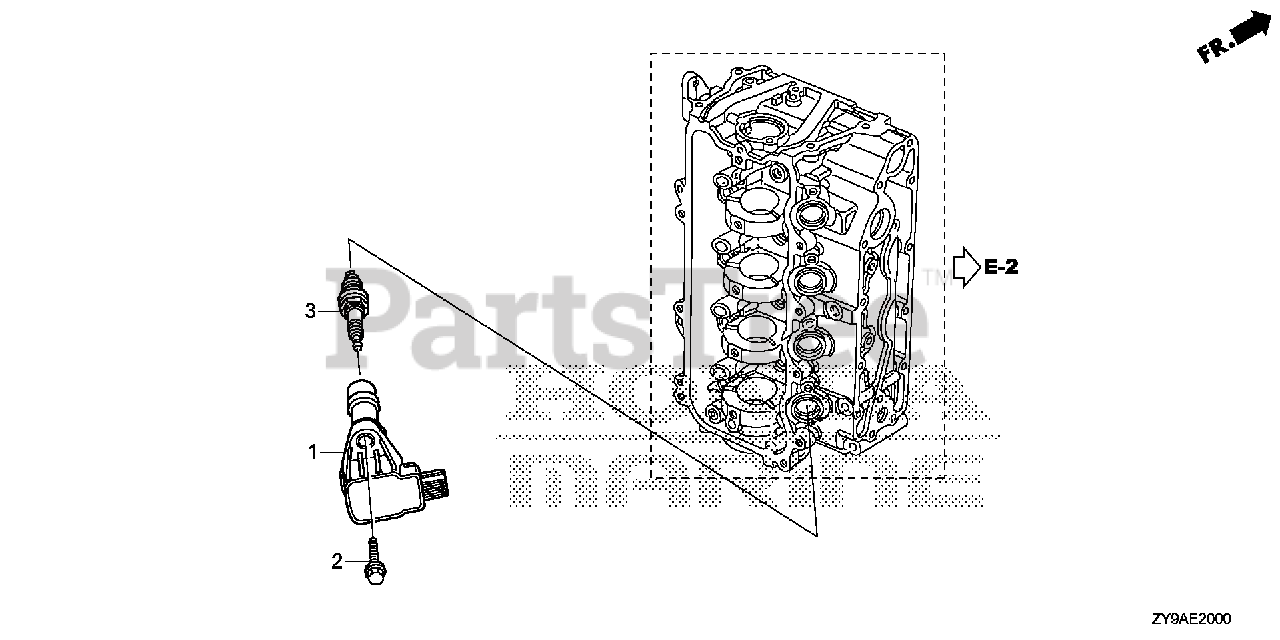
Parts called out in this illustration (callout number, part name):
1	COIL ASSY., PLUG TOP
2	BOLT, FLANGE (6X25)
3	SPARK PLUG (IZFR6K-11E) (NGK)
3	SPARK PLUG (ZFR6K-9E) (NGK)
